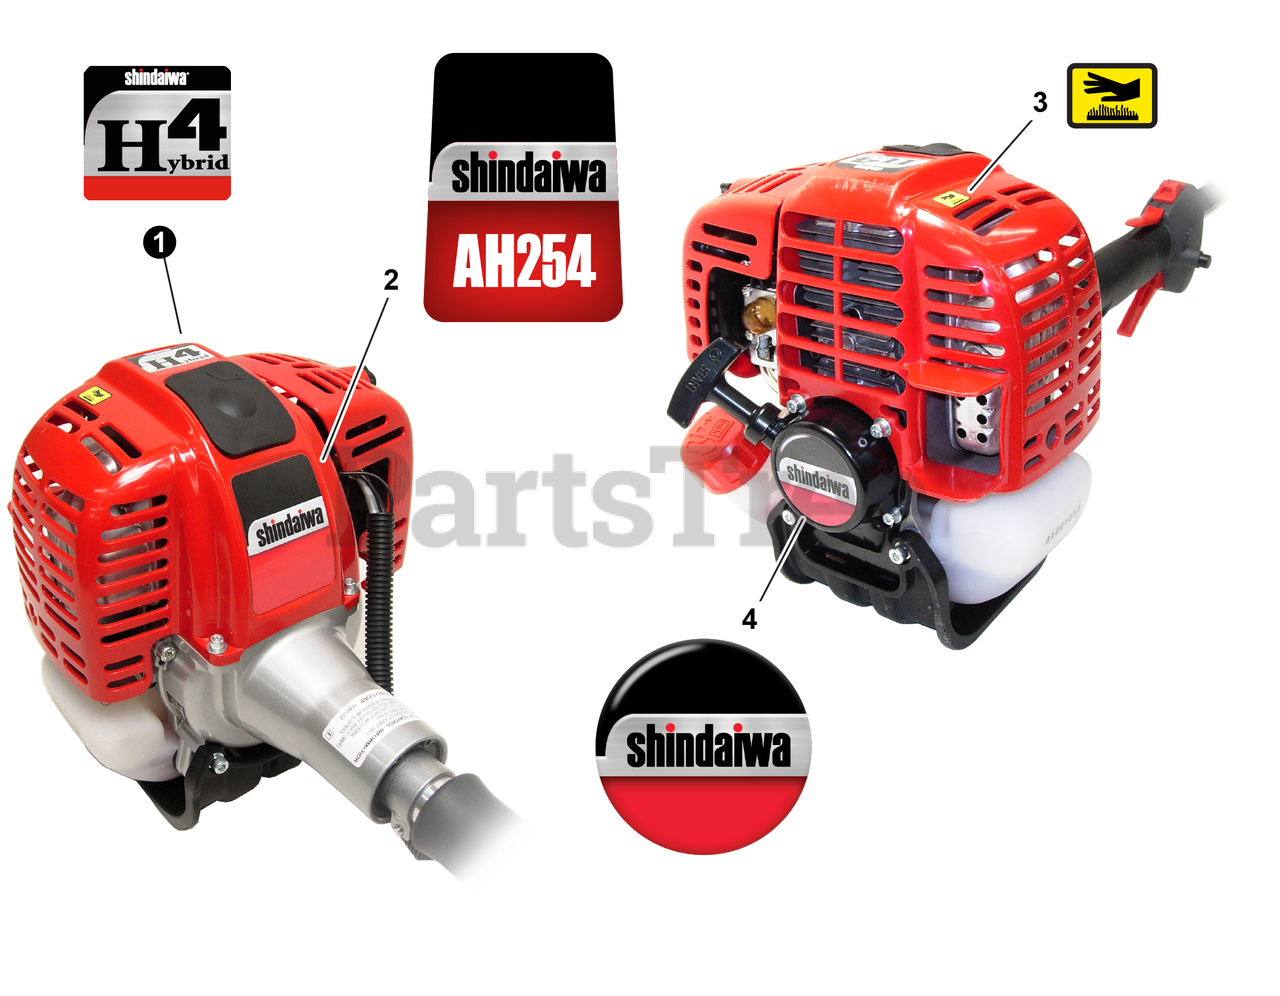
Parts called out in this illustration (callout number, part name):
1	LABEL, shindaiwa H4
2	LABEL, AH254
3	LABEL, CAUTION - HOT
4	LABEL, RECOIL STARTER
